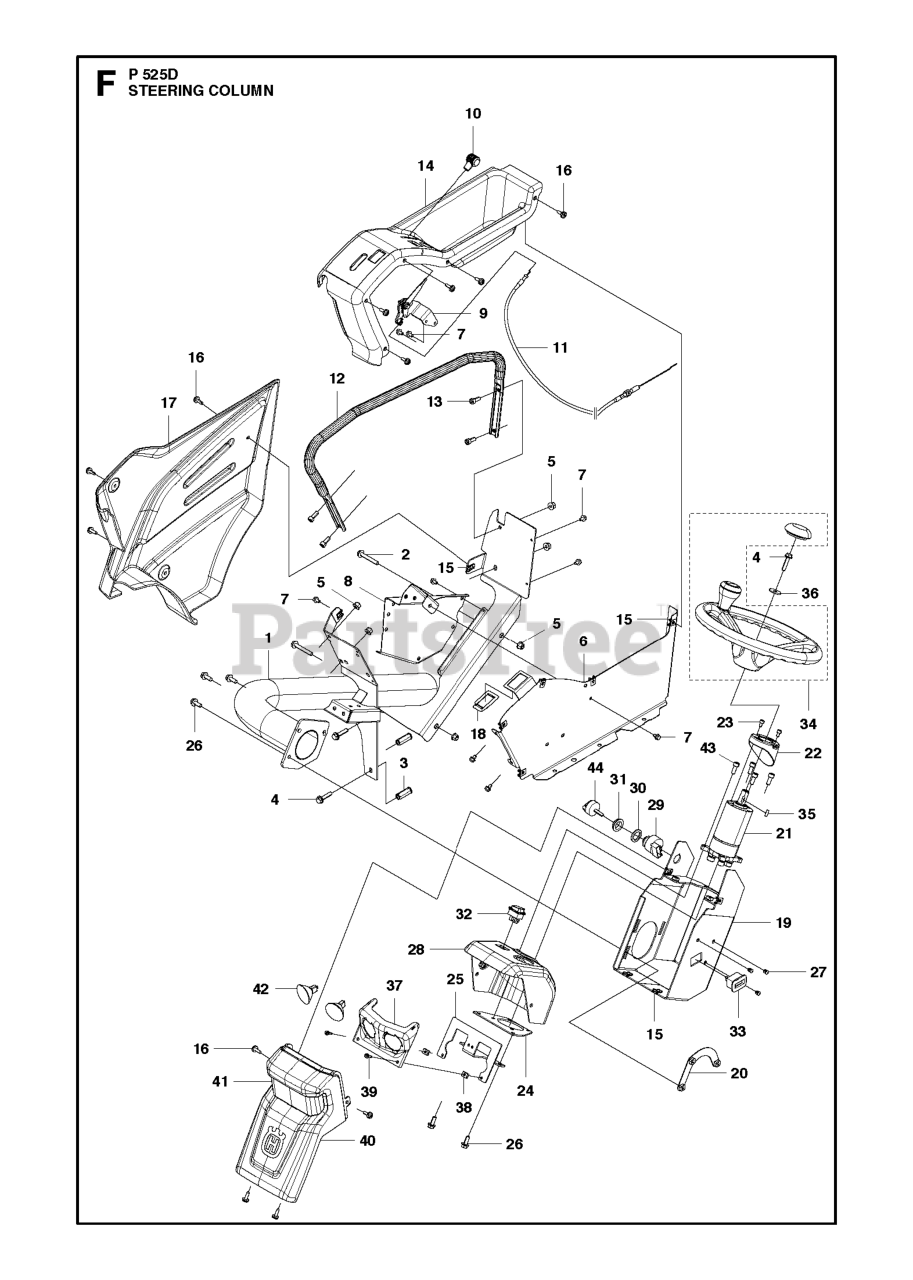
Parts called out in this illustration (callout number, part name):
2	SCREW EHHFM
4	SCREW EHHFM
5	NUT FLANGE
23	SCREW MC6S 6X10
27	INSERT PIPE END
